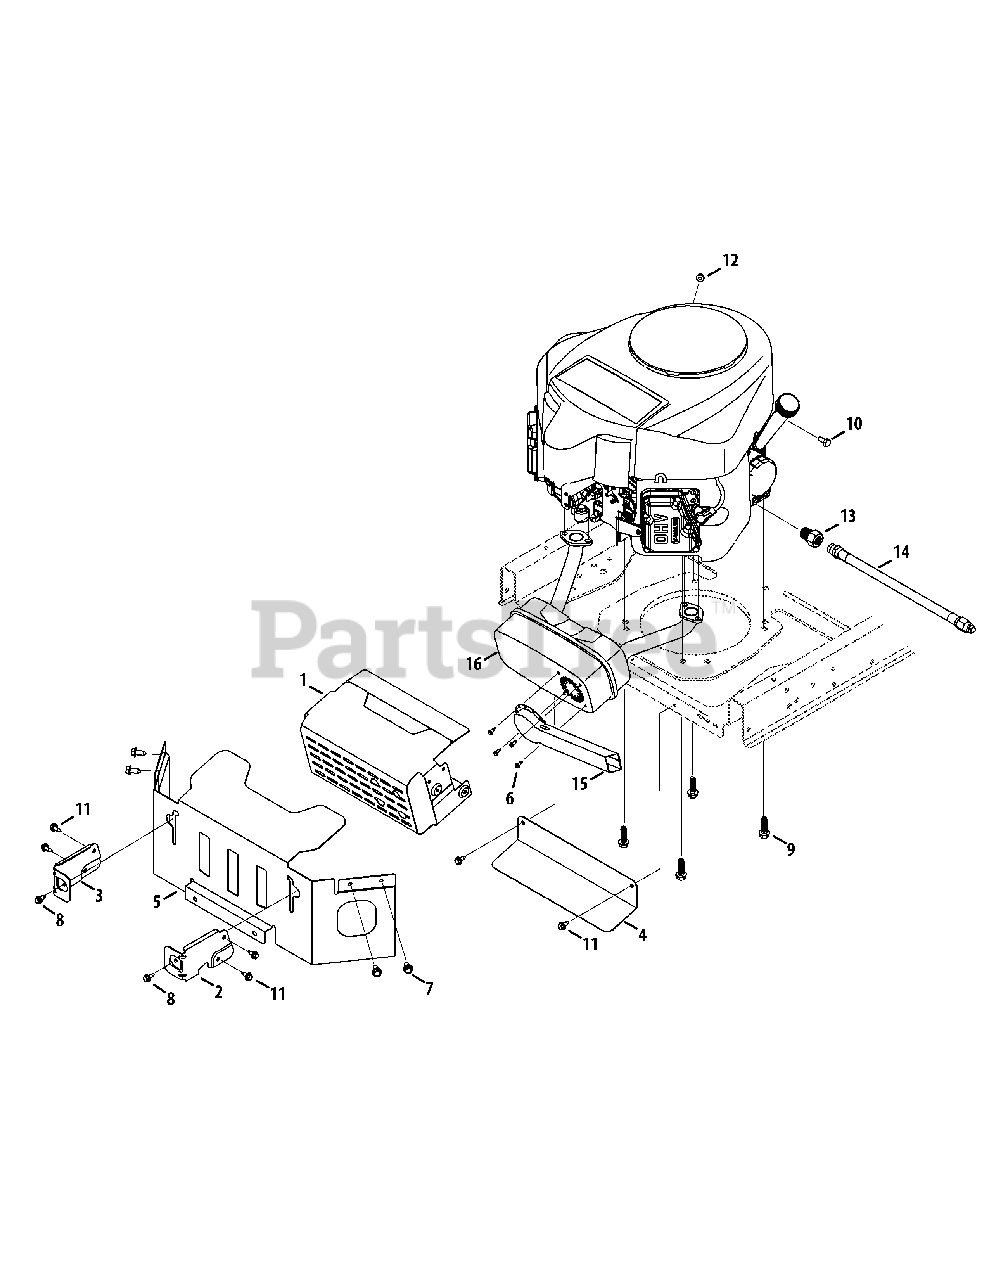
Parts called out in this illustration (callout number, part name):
1	Muffler Shield Assembly
2	Muffler Shield Bracket, RH
3	Muffler Shield Bracket, LH
4	Lower Heat Shield
5	Muffler Shield
6	Hex Washer Screw, #8-18 x .500
7	Hex Washer Screw, 5/16-18 x .750
8	Screw, 1/4-20 x .375
9	Screw, 3/8-16 x 1.25
10	Hex Cap Screw, M8-1.25 x 16
11	Hex Washer Screw, 1/4-20 x .625
12	Flange Lock Nut, 1/4-20
13	Fitting, 1.0 Hex x M20
14	Oil Drain Hose
15	Muffler Deflector Long
16	Twin Muffler
